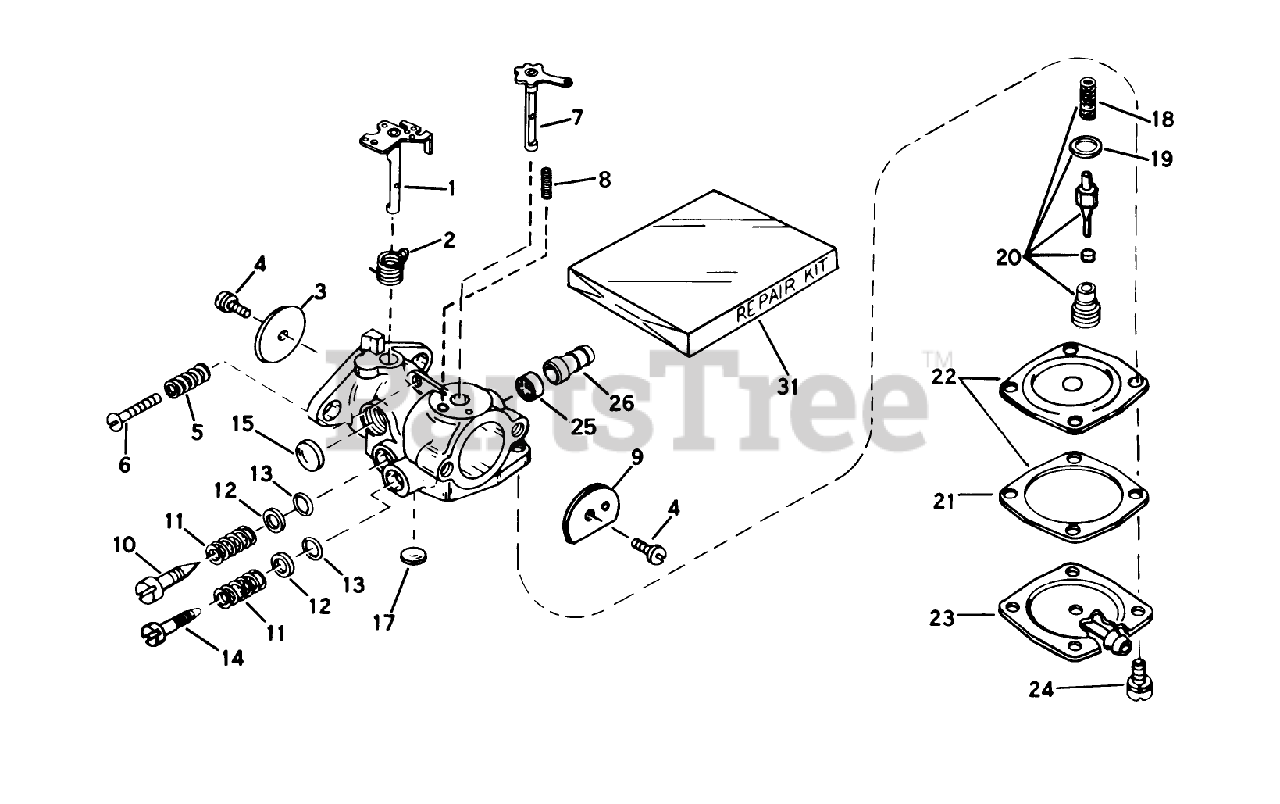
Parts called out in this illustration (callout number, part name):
1	Shaft Lever Assy., Throttle
2	Spring Return
3	Shutter-Throttle
4	Screw-Shutter
5	Spring-Tension
6	Screw-Throttle Crack Screw / Idle Speed
7	Shaft Lever Assembly
8	Spring-Positioning, Choke
10	Screw-Idle Adjustment
10	Screw, Idle Adjustment
11	Spring
12	Washer
13	ORing
14	Screw Main Adjustment
15	Plug-Welch, Idle Mixture Well
17	Plug Welch
18	Spring-Valve
19	Gasket-Valve Seat
20	Inlet Needle, Seat, Spring Gasket Assy. (lncl. #1819)
21	Gasket-Diaphragm
22	Diaphragm Ass. (Incl. No. 21)
23	Cover, Diaphragm
24	Screw, Diaphragm Cover
25	Valve Check
26	Fuel Fitting
31	Kit-Repair
